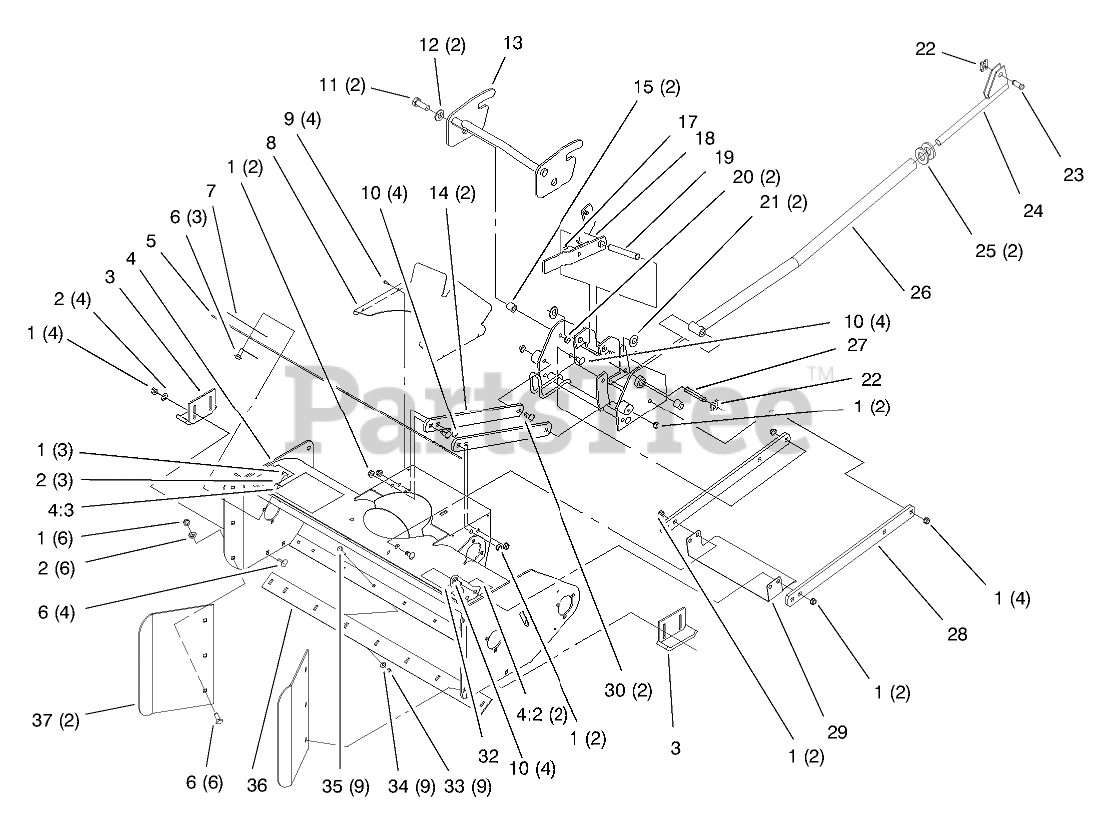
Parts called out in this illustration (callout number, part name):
1	NUT-LOCK, NI
2	WASHER-FLAT
4	Hsg/Decal ASM
4:2	DECAL-DANGER
4:3	DECAL-WARNING
5	PLATE-EXTENSION
6	BOLT-CARR
7	DECAL-ATTACHMENT
8	Shield-Snow
9	SCREW-TAPTITE
10	Bolt
11	SCREW-HH
12	WASHER-FLAT
13	Mounting ASM
14	Bar-Lift
15	BUSHING-PIVOT
16	WASHER-FLAT
17	FITTING-GREASE
18	Idler Pivot ASM
19	Shaft-Idler Pivot
20	NUT-LOCK, NI
21	RING-RETAINING
22	CLIP-PIN
23	PIN-CLEVIS
24	Rod ASM
25	WASHER-FLAT
26	Tube ASM
27	PIN-CLEVIS
28	Bar-Lift
29	Shield-Lower Snow
30	SCREW-CARR
33	NUT-LOCK, NI
34	WASHER-FLAT
35	SCREW-CARR
36	SCRAPER-REVERSIBLE
37	PLATE-EXTENSION, RH
